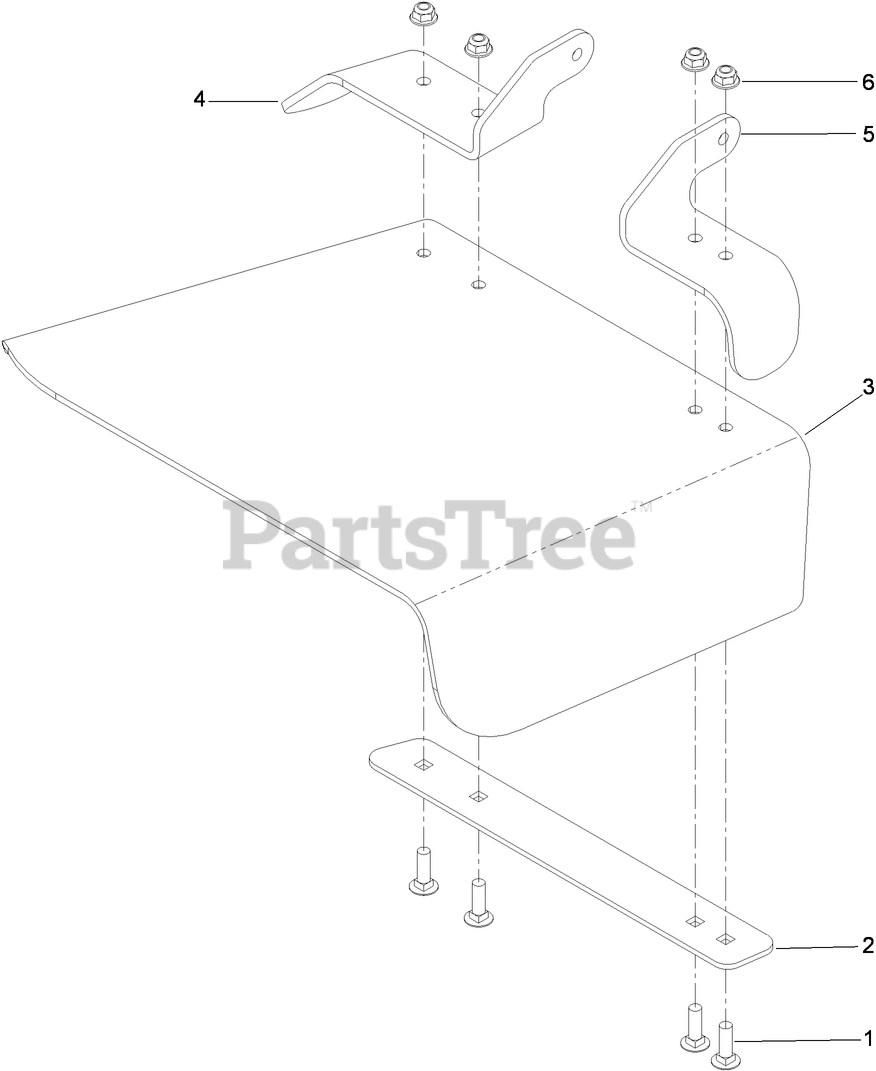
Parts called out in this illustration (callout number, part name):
1	BOLT-CARR
2	STRAP-DISCHARGE
3	DEFLECTOR-RUBBER
4	BRACKET-HINGE, REAR
5	BRACKET-HINGE, FRONT
6	NUT-HF, NI
